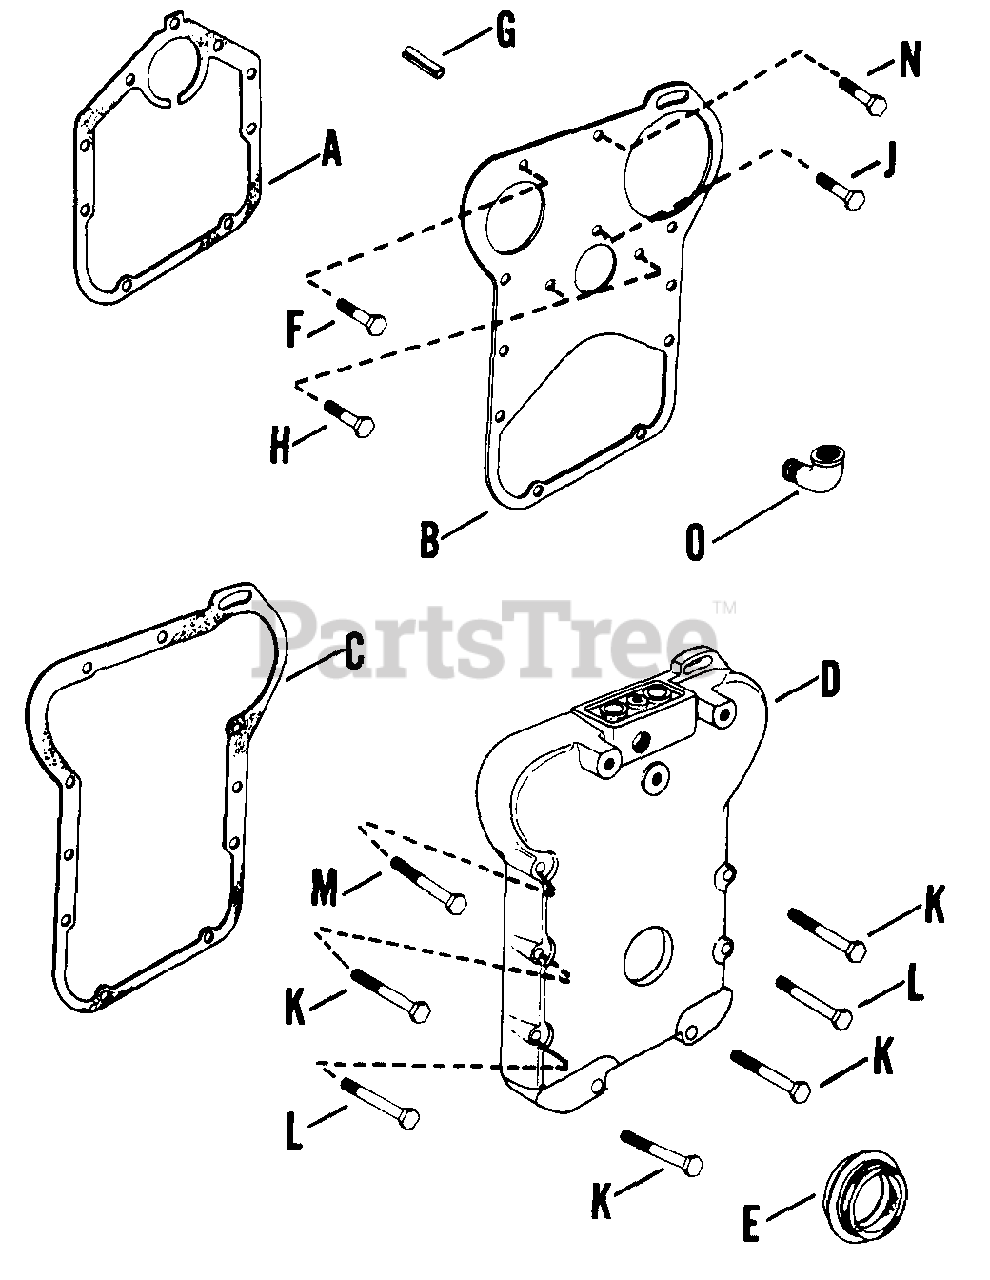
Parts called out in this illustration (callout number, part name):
A	GASKET - DISCONTINUED
B	PLATE - DISCONTINUED
C	GASKET - DISCONTINUED
E	SEAL - DISCONTINUED
F	SCREW, CAP HD 5/16-18x3/4"
J	SCREW,CAP HD 5/16-18x1/2"
K	Screw, hex. hd. 5/16 - 18 x 2-1/4
L	Screw, hex. hd. 5/16 - 18 x 2-1/4
M	SCREW, CAP HD - DISC.
